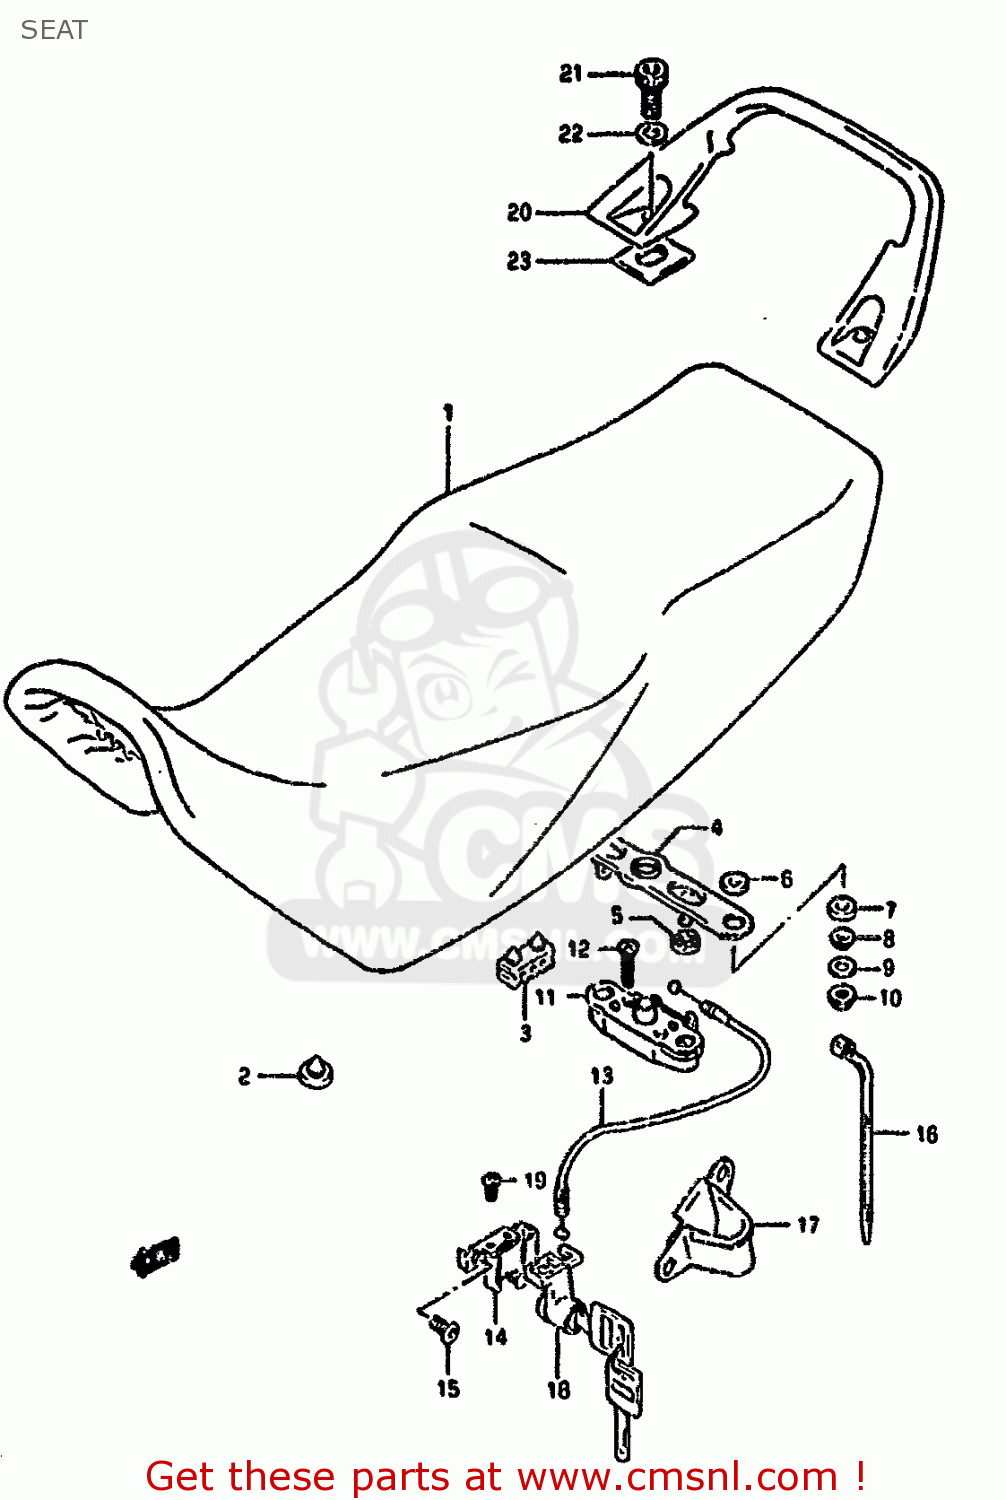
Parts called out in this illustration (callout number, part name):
1	SEAT ASSY
2	CUSHION
3	CUSHION,SEAT(40X20X15)
4	STRIKER,SEAT LOCK
5	CUSHION,SEAT LOCK(10X22X6)
6	CUSHION,UPR
7	CUSHION,LWR
8	WASHER
9	WASHER
10	NUT
11	BRACKET,SEAT SUPPORT,RIGHT
12	SCREW
13	CABLE COMP,SEAT LOCK
14	BRACKET,SEAT LOCK
15	SCREW
16	CLAMP(L:165)
17	PLATE COMP,SEAT LOCK C
18	LOCK SET,SEAT
19	SCREW
20	HANDLE,PILLION RIDER
21	BOLT
22	WASHER
23	CUSHION,FRAME COVER
